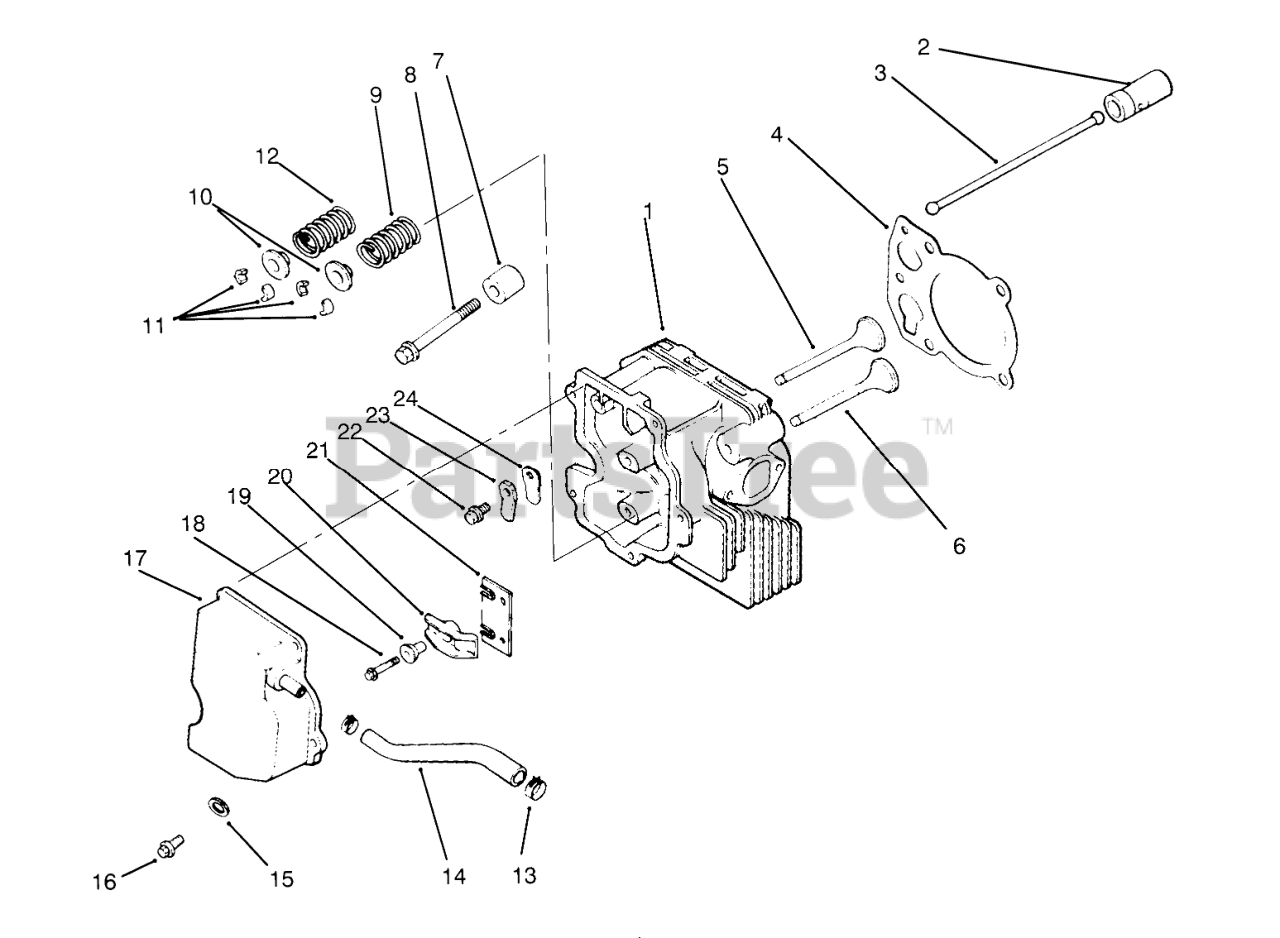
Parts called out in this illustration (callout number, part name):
1	Cylinder Head (Only On: 72042,72043,72062,72063)
2	Lifter-Valve (Only On: 72042,72043,72062,72063)
3	Rod-Push (Only On: 72042,72043,72062,72063)
4	Gasket-Cylinder Head (Only On: 72042,72043,72062,72063)
5	Valve-Intake STD (Only On: 72042,72043,72062,72063)
5	Valve-Intake .25 (Only On: 72042,72043,72062,72063)
6	Valve-Exhaust STD (Only On: 72042,72043,72062,72063)
6	Valve-Exhaust .25 (Only On: 72042,72043,72062,72063)
7	Spacer-Head Bolt Exhaust (Only On: 72042,72043,72062,72063)
8	Screw M10x1.5x80 (Only On: 72042,72043,72062,72063)
9	Spring-Valve Exhaust (Only On: 72042,72043,72062,72063)
10	Cap-Valve Spring (Only On: 72042,72043,72062,72063)
11	Kit-Retainer (Only On: 72042,72043,72062,72063)
12	Spring-Valve Intake (Only On: 72042,72043,72062,72063)
13	Clamp-Hose (Only On: 72042,72043,72062,72063)
14	Hose-Breather (Only On: 72042,72043,72062,72063)
15	Washer-Flat (Only On: 72042,72043,72062,72063)
16	Screw M6x1.0x20 (Only On: 72042,72043,72062,72063)
17	Cover-Valve W/Nipple (Only On: 72042,72043,72062,72063)
18	Screw M6x1.0x34 (Only On: 72042,72043,72062,72063)
19	Ball-Rocker Pivot (Only On: 72042,72043,72062,72063)
20	Arm-Rocker (Only On: 72042,72043,72062,72063)
21	Plate-Guide (Only On: 72042,72043,72062,72063)
22	Screw M5x0.8x10 (Only On: 72042,72043,72062,72063)
23	Retainer-Breather Reed (Only On: 72042,72043,72062,72063)
24	Reed-Breather (Only On: 72042,72043,72062,72063)
